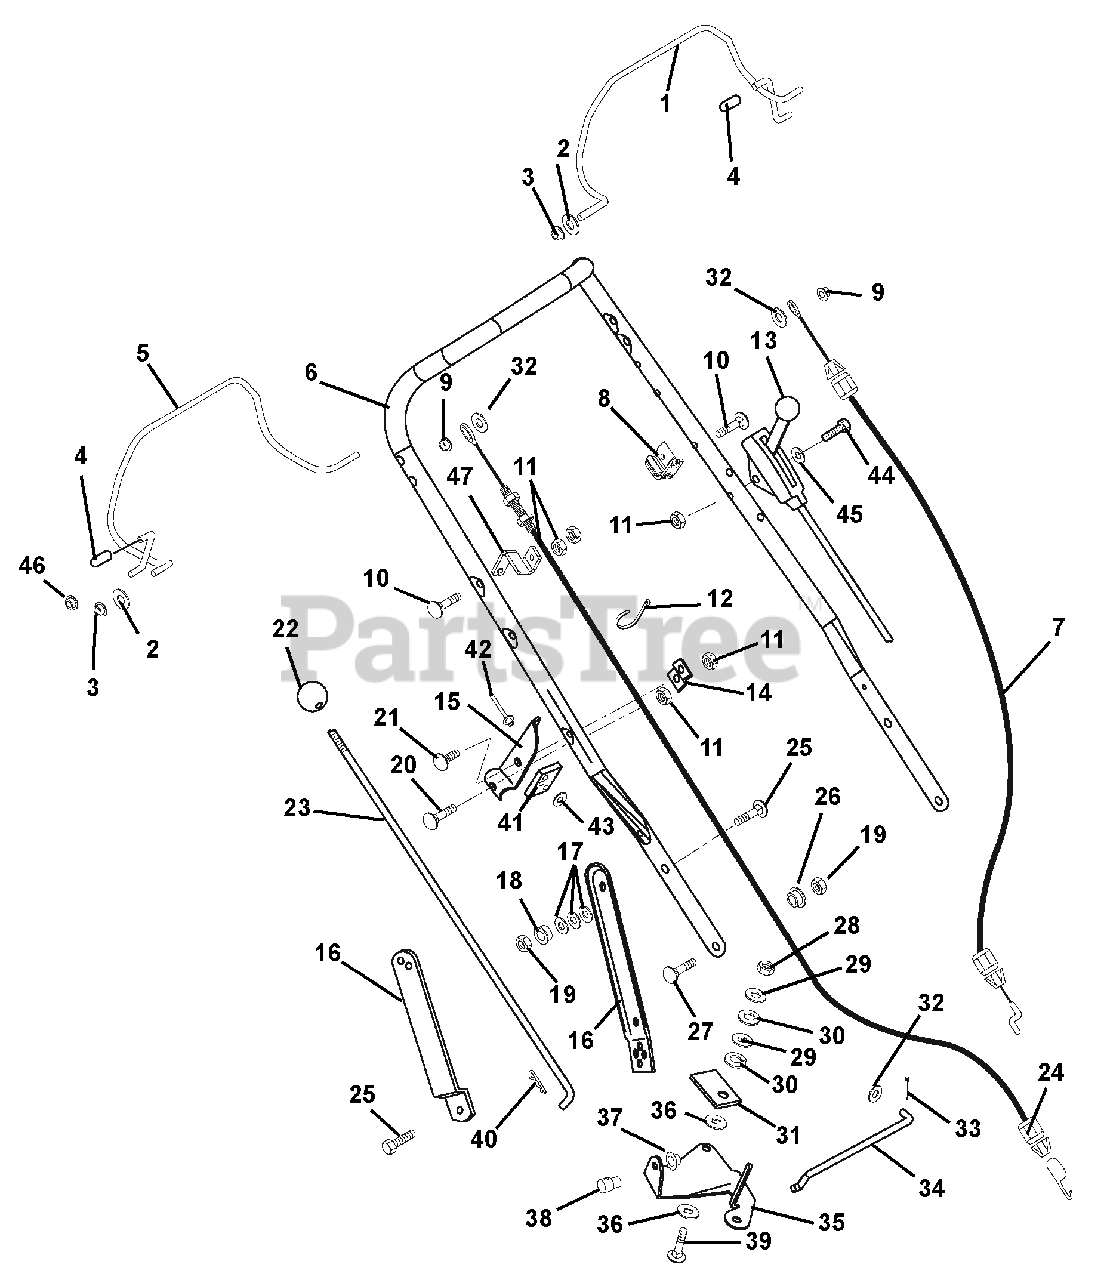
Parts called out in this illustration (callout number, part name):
1	BAIL, ENGINE WELDMENT
2	@WSHR-FL-STL.344X.688X.065YWZC
3	BSHG-FLG .325X.444X.440X.560
4	CAP, VINYL, .25 ID
5	BAIL, TRACTION (WLDMENT)
6	BAR, WBLM HANDLE
7	CABLE, ENGINE (BRIGGS/GXV)
7	CABLE, WBLM ENGINE
7	CABLE, ENGINE - ADJUSTABLE
8	ANCHOR, WBLM ENGINE CABLE
9	PUSH NUT, .25
10	BLT-RDHDXLSQNK.25-20X1.25 G5ZC
11	@NUT-LK-CTR .25-20 YWZC
12	CABLE TIE LG 5-1/2
13	CABLE, LOCKOUT CONTROL
14	BRACE, SPEED CONTROL
15	BRACKET, SPEED CONTROL
16	LINK, HANDLEBAR ADJUSTMENT LH
16	LINK, HANDLEBAR ADJUSTMENT RH
17	WASHER, BELLEVILLE YWZC
18	BSHG-FLG .325X.500X.513X.875
19	@NUT-LK-CTR .31-18 YWZC
20	@BLT-RDHDSQNK .25-20X1.50 G5YZ
21	@BLT-RDHDSQNK .25-20X.50 G5YZ
22	KNOB, BALL 5/16-18 X 1.5
23	ROD-SPEED CONTROL
24	CABLE, WBLM TRACTION
25	@BLT-RDHDSQNK .31-18X1.00 G5YZ
26	BSHG, FLG .325X.499X.26X.88
27	@BLT-RDHDSQNK .31-18X.75 G5YZ
28	@NUT-LK-CTR .38-16 YWZC
29	@WSHR-FL-STL.406X.812X.065 YWZ
30	WSHR-LK .375X.115 HVY YWZC
31	PRESSURE FLANGE
32	@WSHR-FL-STL.281X.62X.065 YWZC
33	@PIN-CTR .06X.50 EXTPRSQCT YWZ
34	SHIFT LINK
35	BELL CRANK - SPEED CONTROL
36	FRICTION WASHER
37	CAP, 3/8 ROD YWZC
38	SWIVEL
39	@BLT-RHDSSQNK .38-16X1.25 G5YZ
40	PIN-HAIR INT .08X.18X1.18 YWZC
41	SUPPORT PAD
42	RVT .187X.575 DOME AL BLACK
43	@WSHR-FL-STL.219X.50X.049 YWZC
44	BLT-RDHDSQNK .25-20X1.75 G5YZ
45	@WSHR-FL-STL.250X.56X.049 YWZC
46	NUT-PUSH .312 DIA. PAL
47	ANCHOR, CABLE
